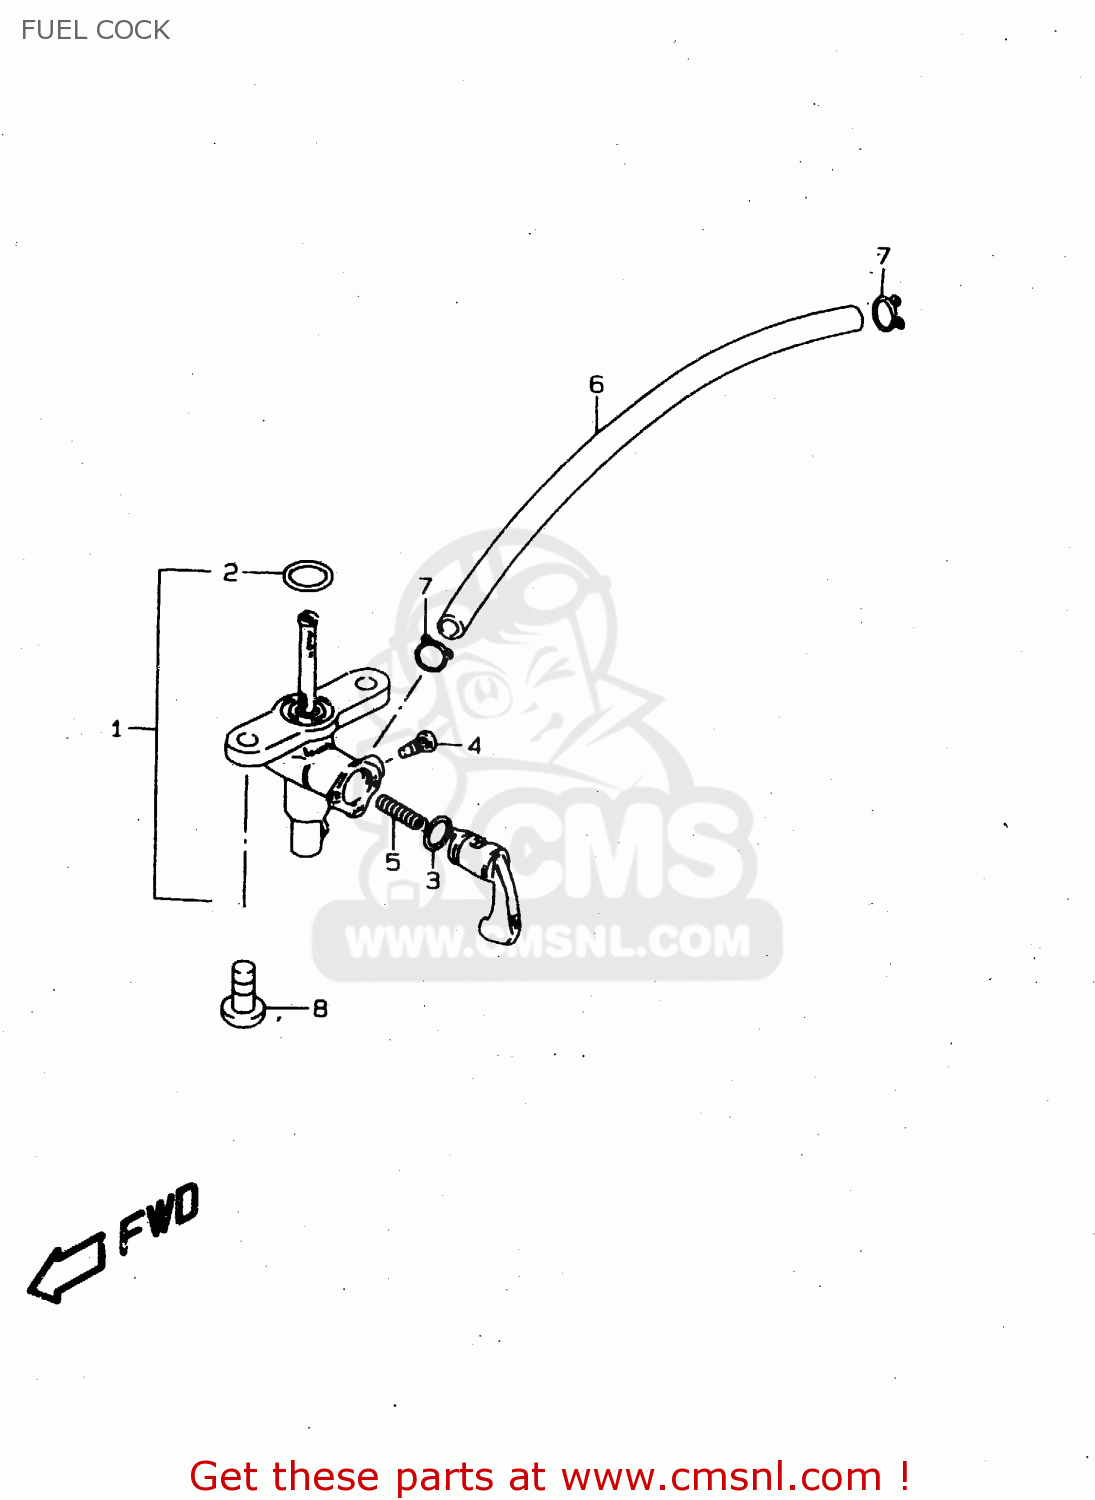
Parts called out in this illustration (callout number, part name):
1	COCK ASSY,FUEL
2	O RING
3	O RING,LEVER
4	SCREW
5	SPRING
6	HOSE(5X8.2X600)
7	CLIP
8	SCREW
